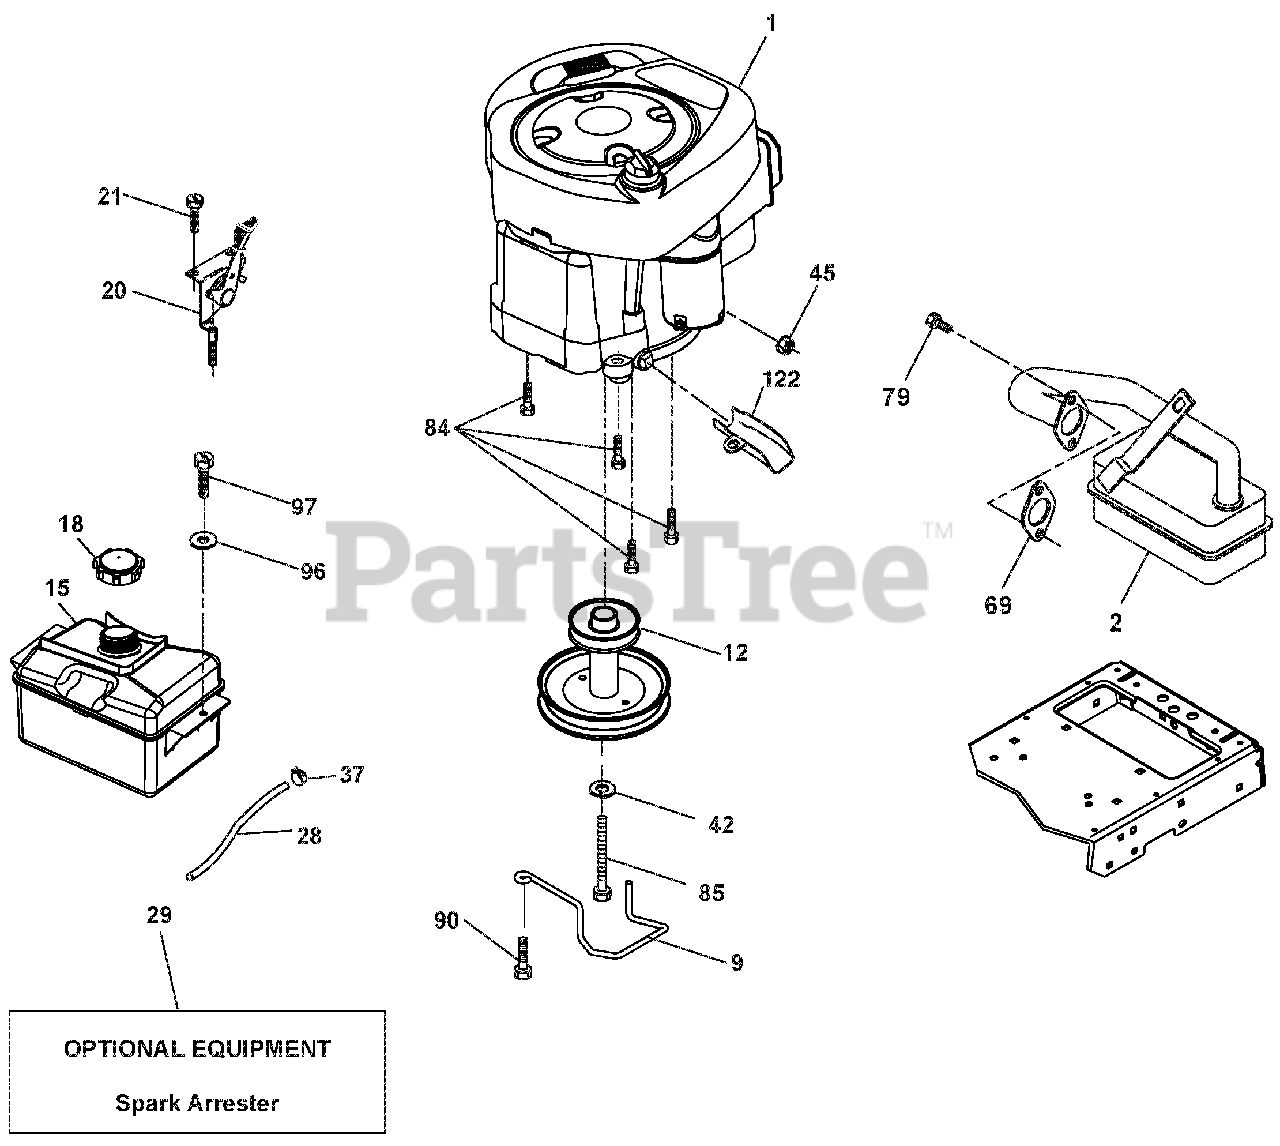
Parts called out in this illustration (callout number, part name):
1	ENGINE BRIGGS MODEL NO. 31R977-0024-G1(586254701)(ORDER PARTS FROM ENGINE MANUFACTURER.)
2	Muffler Exhaust B&S
9	KEEPER.BELT.ENGINE.3.25"NSTL
12	ENGINE PULLEY
15	TANK FUEL
18	CAP FUEL
20	CONTROL.THROTTLE
28	LINE.FUEL.20"
29	KIT.SPARK ARRESTOR(392390 B&S)
37	CLAMP.HOSE.BLK.
42	WASHER.LOCK.HVY HLCL.SPR.7/16
45	Nut, Keps Hex 1/4-20 unc
69	Gasket Eng 1 313 Id Tin Plated
79	SCREW.SOCKET HD.5/16-18 X .75
84	Screw 3/8-16 x <
85	BOLT.HEX.7/16-20X4XGR5-1.5THR.
90	SCREW.3/8-16X1.SMGML.TAP/R.BLK
96	WASHER.9/32 X 7/8 X 16GA.
97	SCREW.HEXWSH.THDROL.1/4-20X3/4
122	Extension Drain Oil
